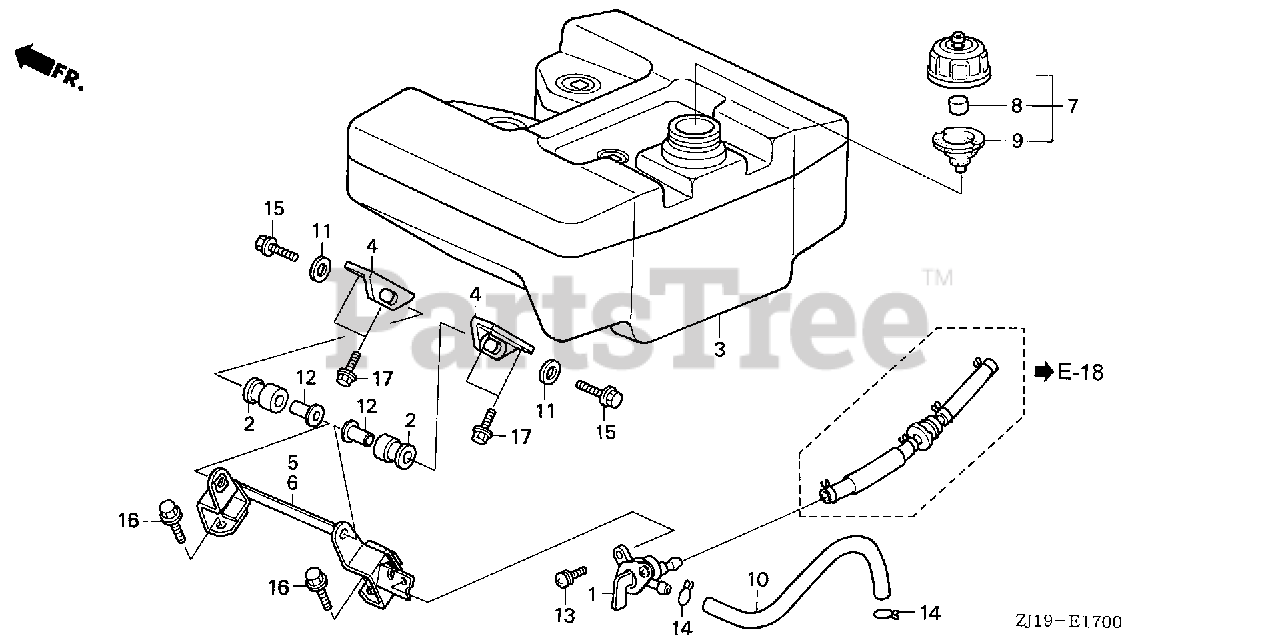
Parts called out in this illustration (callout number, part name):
1	PETCOCK ASSY.
2	RUBBER, TANK MOUNTING
3	TANK COMP., FUEL
4	BRACKET, FUEL TANK
5	STAY, R. FUEL TANK
6	STAY, L. FUEL TANK
7	CAP ASSY., FUEL TANK
8	SPONGE, FUEL CAP BREATHER
9	GASKET, FUEL CAP
10	TUBE, FUEL
11	WASHER, PLAIN (6MM)
12	COLLAR, TANK SETTING
13	SCREW-WASHER (5X14)
14	CLIP, TUBE (B10)
15	BOLT, FLANGE (6X45)
16	BOLT, FLANGE (8X20)
17	BOLT, FLANGE (6X16)
